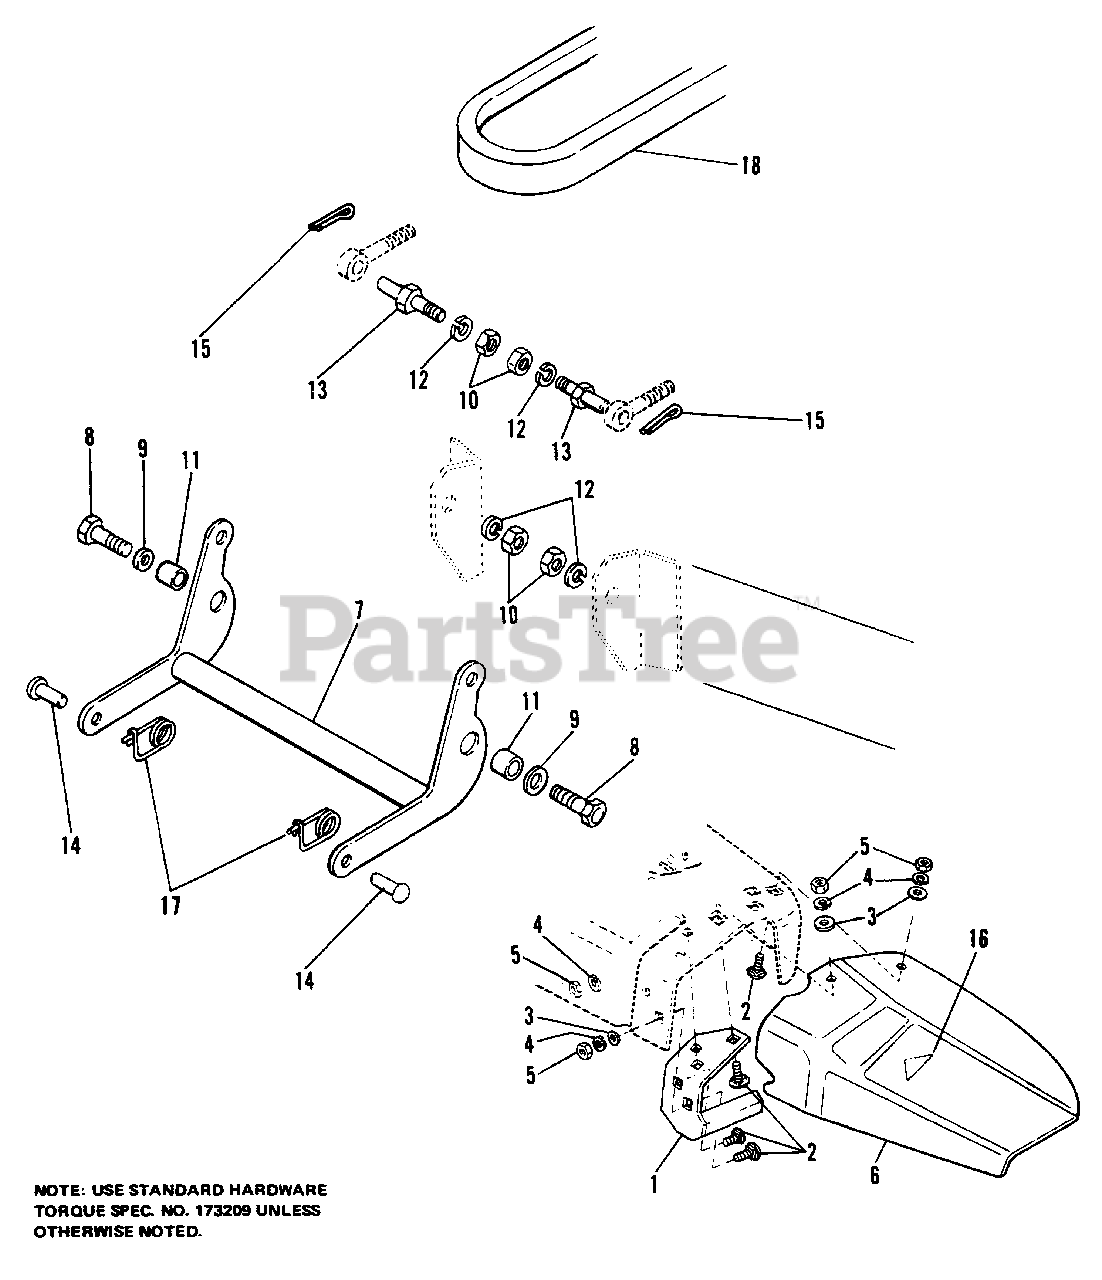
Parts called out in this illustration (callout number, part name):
1	GUARD ASSY, Stone
2	BOLT, Carriage, 3/8-16 x 1-1/4
3	WASHER, Special
4	LOCKWASHER, 3/8
5	NUT, Hex, full, 3/8-16
6	DEFLECTOR
7	ROCKER ARM ASSY
8	CAPSCREW, Hex Hd., 1/2-13 x 1-1/4
9	WASHER, Plain, 7/16
10	NUT, Hex, Full, 1/2-13
12	LOCKWASHER, 1/2
14	PIN
15	PIN, Cotter, 1/8 x 1
16	DECAL, OPEI
17	PIN, Clip
18	BELT, V, PTO to Mower
